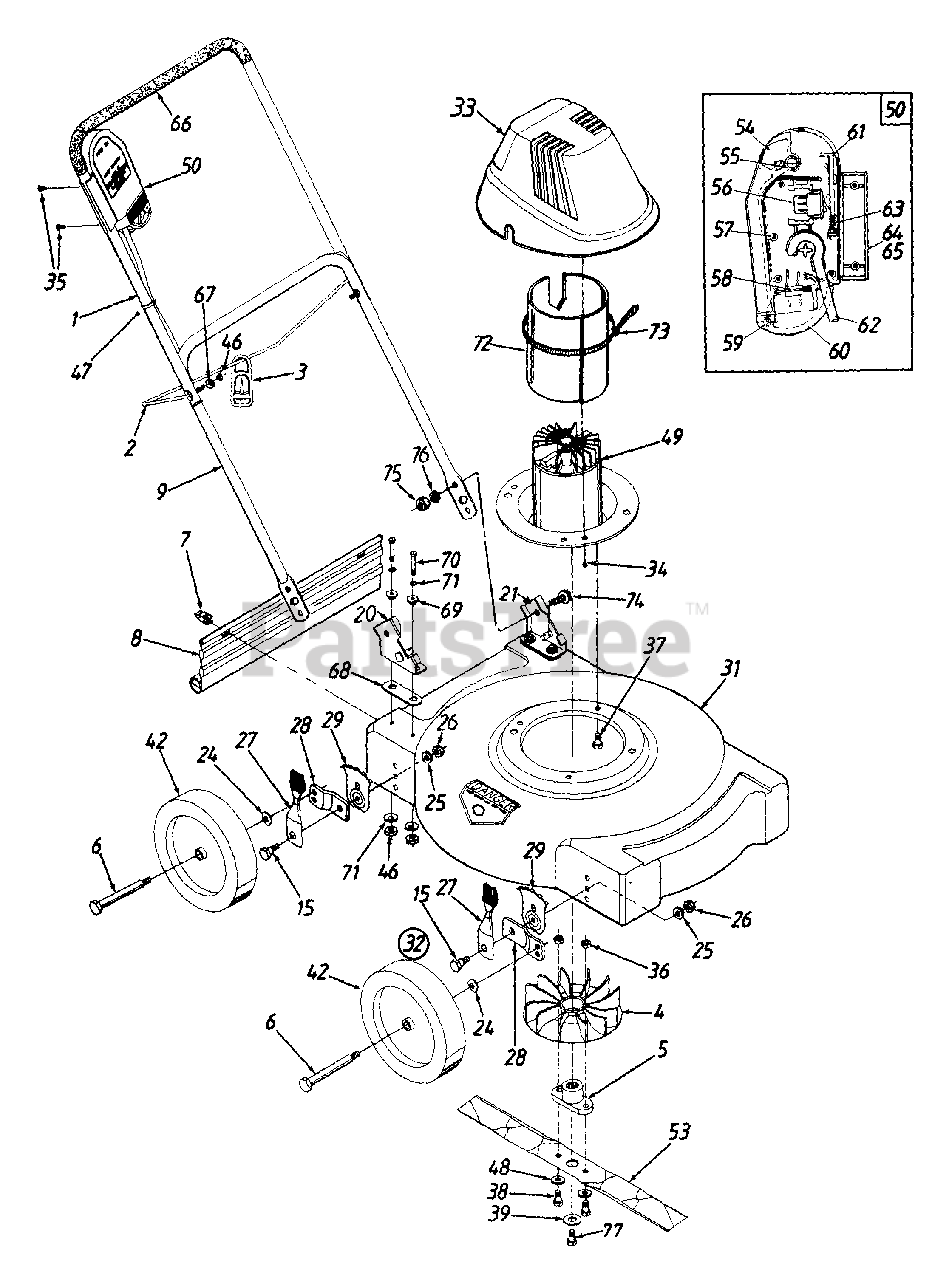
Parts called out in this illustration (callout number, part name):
1	Upper Handle
2	Cord Control Rod
3	Strain Relief - Cord
5	Blade Adapter
6	Axle Bolt
7	Hinge Clip
8	Rear Flap
15	Shld. Bolt .5" Dia. x .434"
20	Handle Brkt. Ass'y.- R.H.
21	Handle Brkt. Ass'y.- L.H.
24	Bell-Wash..38" I.D. x.88" O.D.
25	Bell-Wash..39" I.D. x 1.38" O.D.
26	Hex Nut 3/8-16 Thd.
27	Spring Lever Ass'y. w/Knob
28	Pivot Bar
29	Height Adj. Plate
31	20" Deck Ass'y.
32	Height Adj. Ass'y. Comp.- R.F. & L.R.
33	Motor Cover
34	Scr. #10-16 x .75" Lg.
35	Self-Tap. Scr. #7 x 1" Lg.
36	Hex Nut 3/8-24 Thd.
37	Hex L-Wash. TT-Tap Scr. 3/8-16 x .75" Lg.
38	Hex Bolt 3/8-24 x 1.25" Lg.
39	Bell-Wash..396" I.D. x 1.14" O.D.
42	Wheel Ass'y Comp.
46	Hex Top L-Nut 1/4-20 Thd
47	Cable Tie
48	L-Wash. 3/8" I.D.
49	Motor, Cord & Switch Ass'y.
50	Cord & Switch Ass'y Comp. (See Breakdown)
53	20" Mulching Blade
54	Handle - Switch Actuator
55	Spring - Switch Handle
56	Switch
57	Screw #6-32 x 5" Lg.
58	Plug Ass'y.
59	Retainer Plug Spring
60	Retainer Plug
61	Latch
62	Cord Ass'y
63	Spring Latch
64	Housing - Upper Half
66	Foam Grip
67	Curved Wash. 5/16" I.D.
68	insulator Strip
69	Insulator Shield
70	Hex Bolt 1/4-20 x 1" Lg.
71	Fl-Wash..26" I.D. x.72" O.D.
72	Insulator
73	Cable Tie
74	Phillips Hd. Scr. 5/16 x .75" Lg.
75	Hex Nut 5/16-18 Thd.
76	L-Wash. 5/16" I.D.
77	Hex Bolt 3/8-24 x 2.5" Lg.
